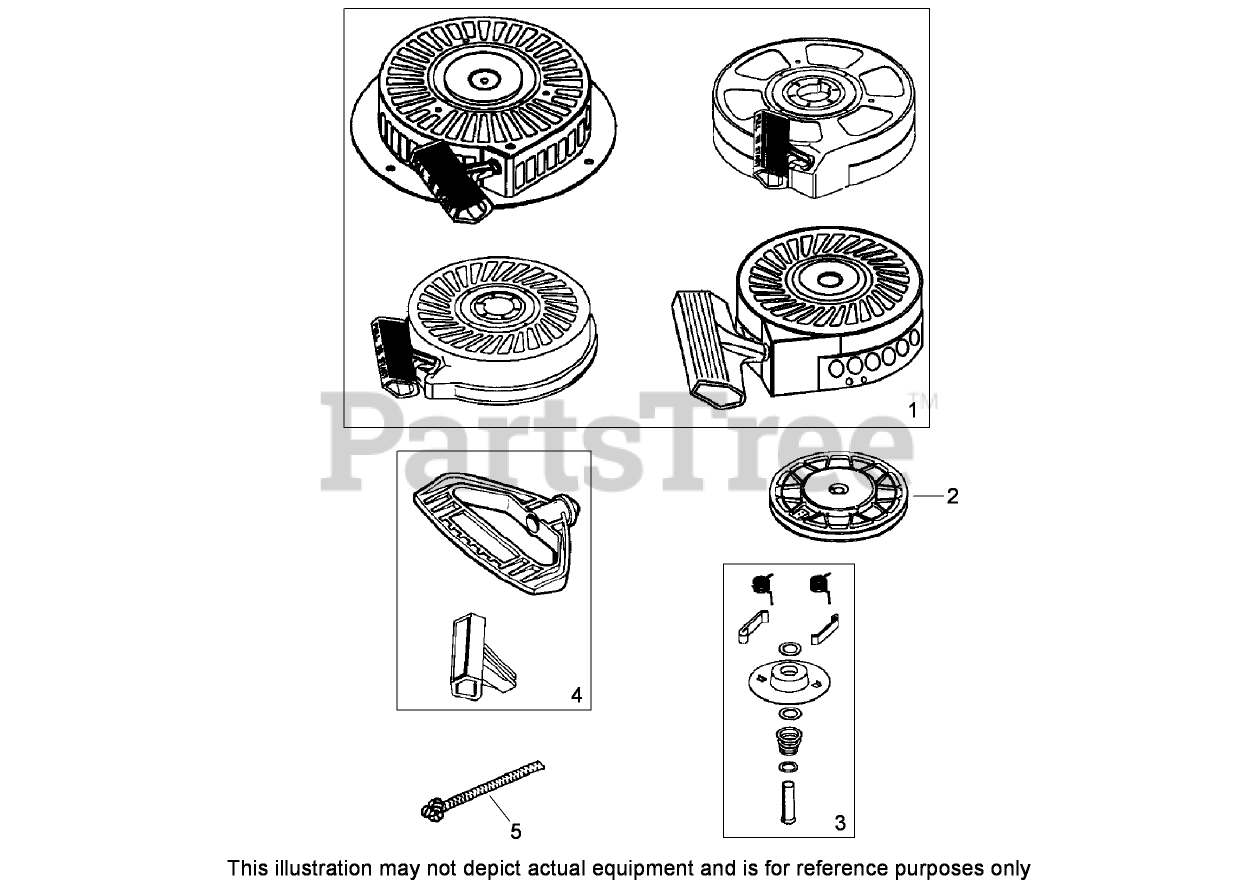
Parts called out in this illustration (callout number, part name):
1	Starter-Rewind
2	Pulley and Rewind Spring ASM
3	Repair Kit
4	Handle-Starter, Mitten Grip
5	Rope-Starter (98 cut to length)
